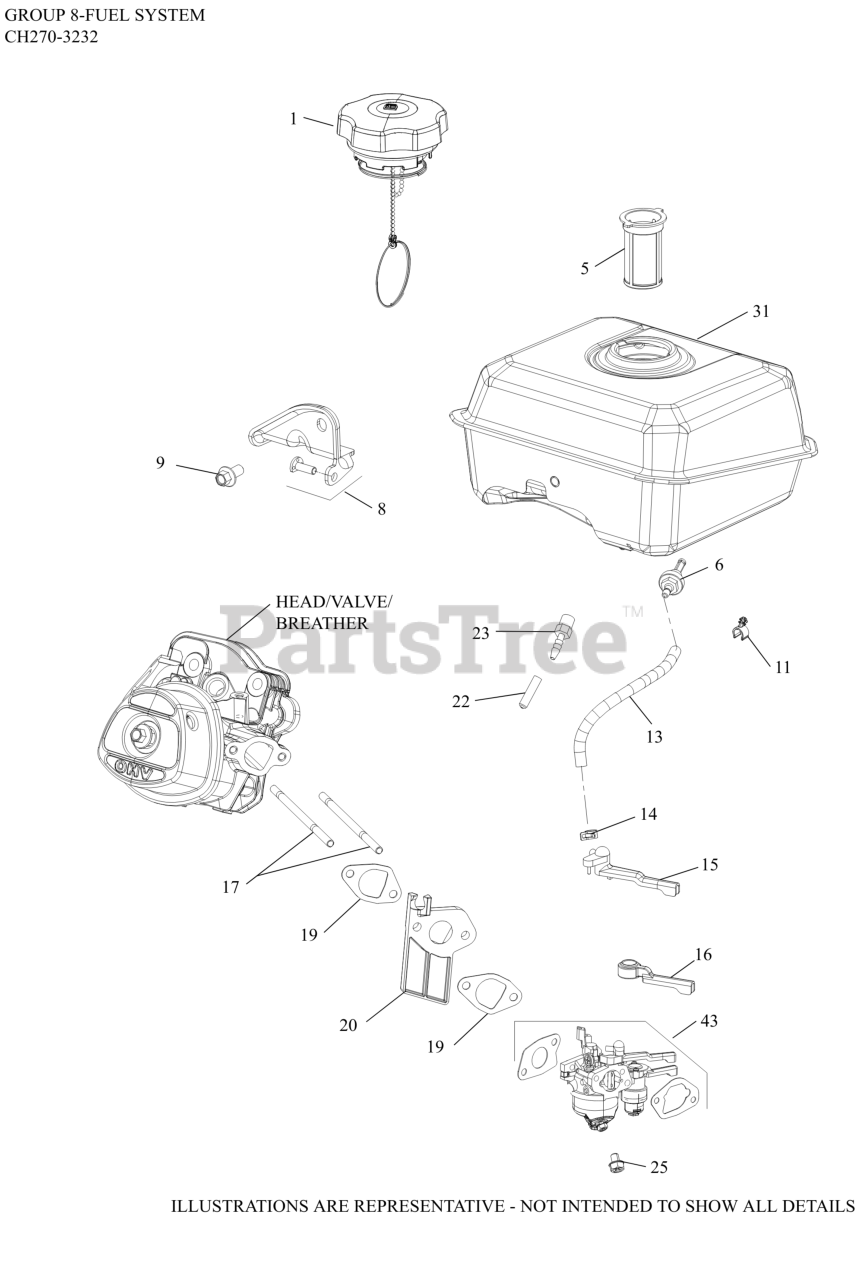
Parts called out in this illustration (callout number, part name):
1	CAP, FUEL ASSEMBLY
5	FILTER, FUEL TANK
6	FITTING, FUEL ASSY
8	BRACKET ASSY, FUEL TANK
9	SCREW, FLG 8X1.25X16
11	CLIP, FUEL HOSE
13	LINE, FUEL (10"-CUT TO LENGTH)
14	CLAMP, FUEL LINE
15	LEVER, CHOKE
16	LEVER, FUEL SHUTOFF
17	STUD, CARBURETOR
19	KIT, INTAKE GASKET
20	KIT, CARBURETOR INSULATOR
25	SCREW, BOWL DRAIN
31	KIT, FUEL TANK
43	KIT, CARBURETOR COMPLETE
NI	KIT, HIGH ALTITUDE (4,000-8,000 FT)
NI	KIT, HIGH ALTITUDE (ABOVE 8,000 FT.)
NI	KIT, CARBURETOR REPAIR (RUIXING)
